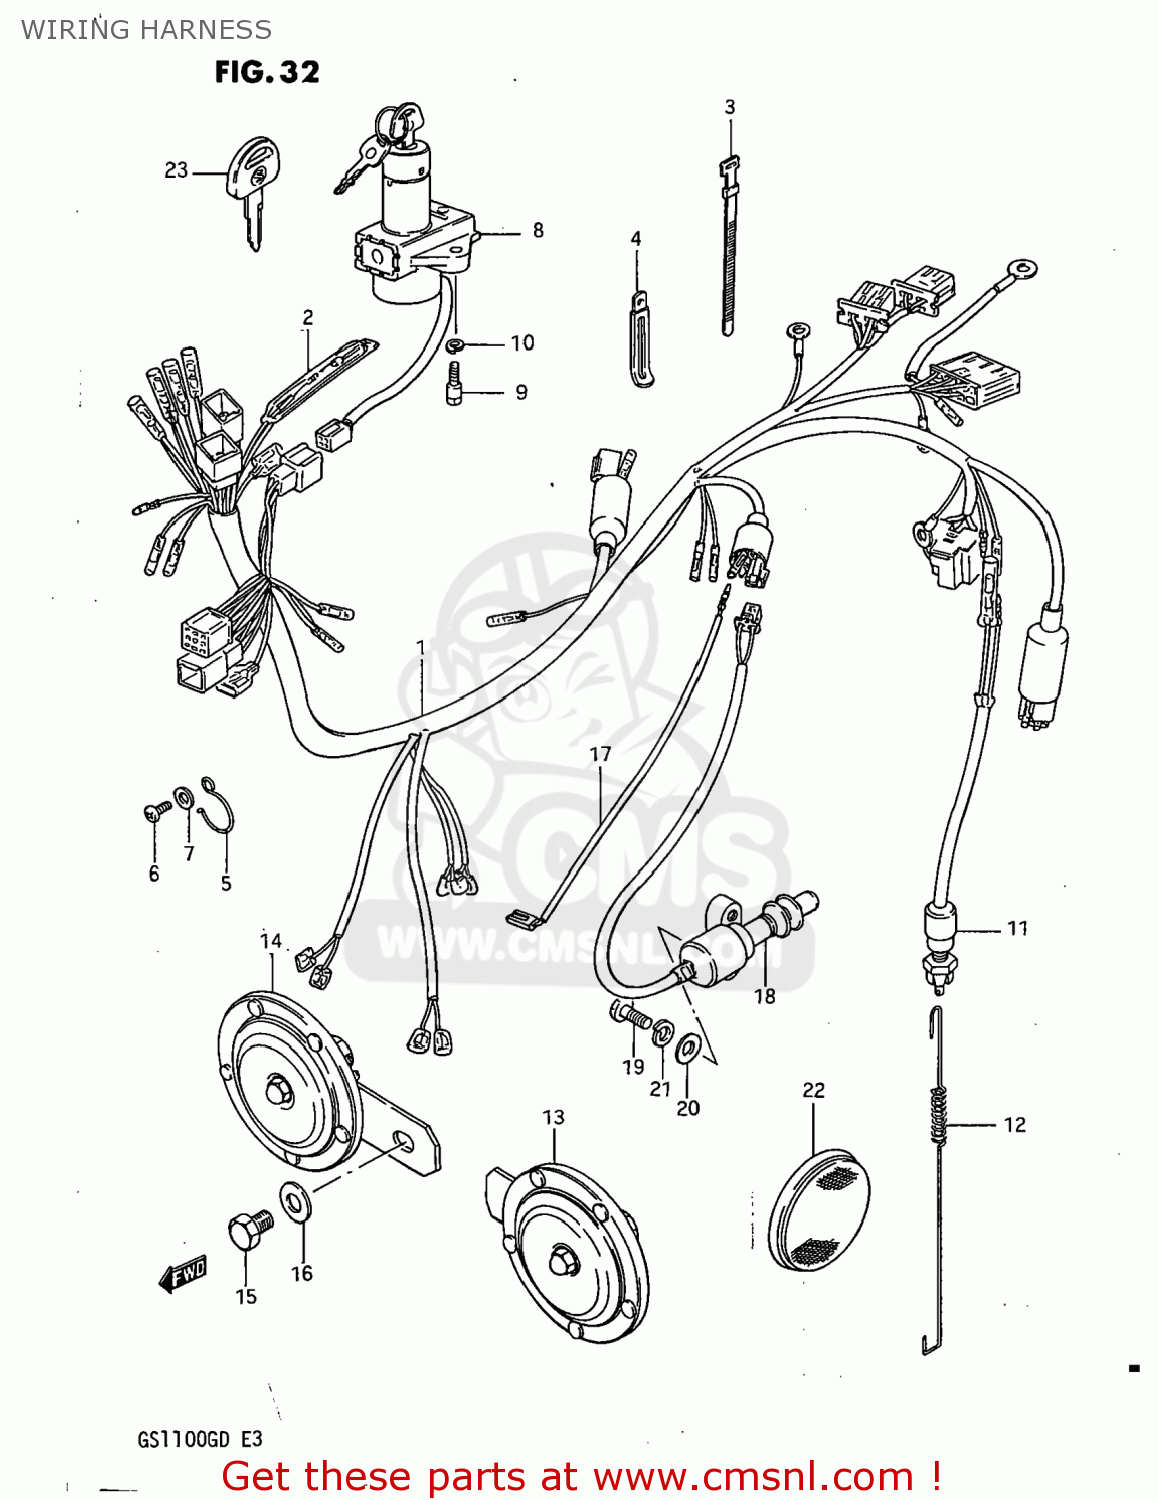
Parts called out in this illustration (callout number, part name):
1	HARNESS,WIRING
2	DIODE
3	CLAMP(L:120)
4	CLAMP
5	CLIP,WIRING HARNESS
6	SCREW 6X12
7	WASHER
8	SWITCH ASSY,IGNITION
9	BOLT
10	LOCK WASHER
11	SWITCH ASSEMBLY,STOP LAMP
12	SPRING
13	HORN ASSEMBLY,LOW PITCH
14	HORN ASSEMBLY,HIGH PITCH
15	BOLT
16	WASHER
17	WIRE,OIL PRESSURE SWITCH LEAD
18	SWITCH ASSEMBLY,SIDE STAND
19	BOLT
20	WASHER
21	LOCK WASHER
22	REFLEX REFLECTOR,RR
23	KEY,BLANK
